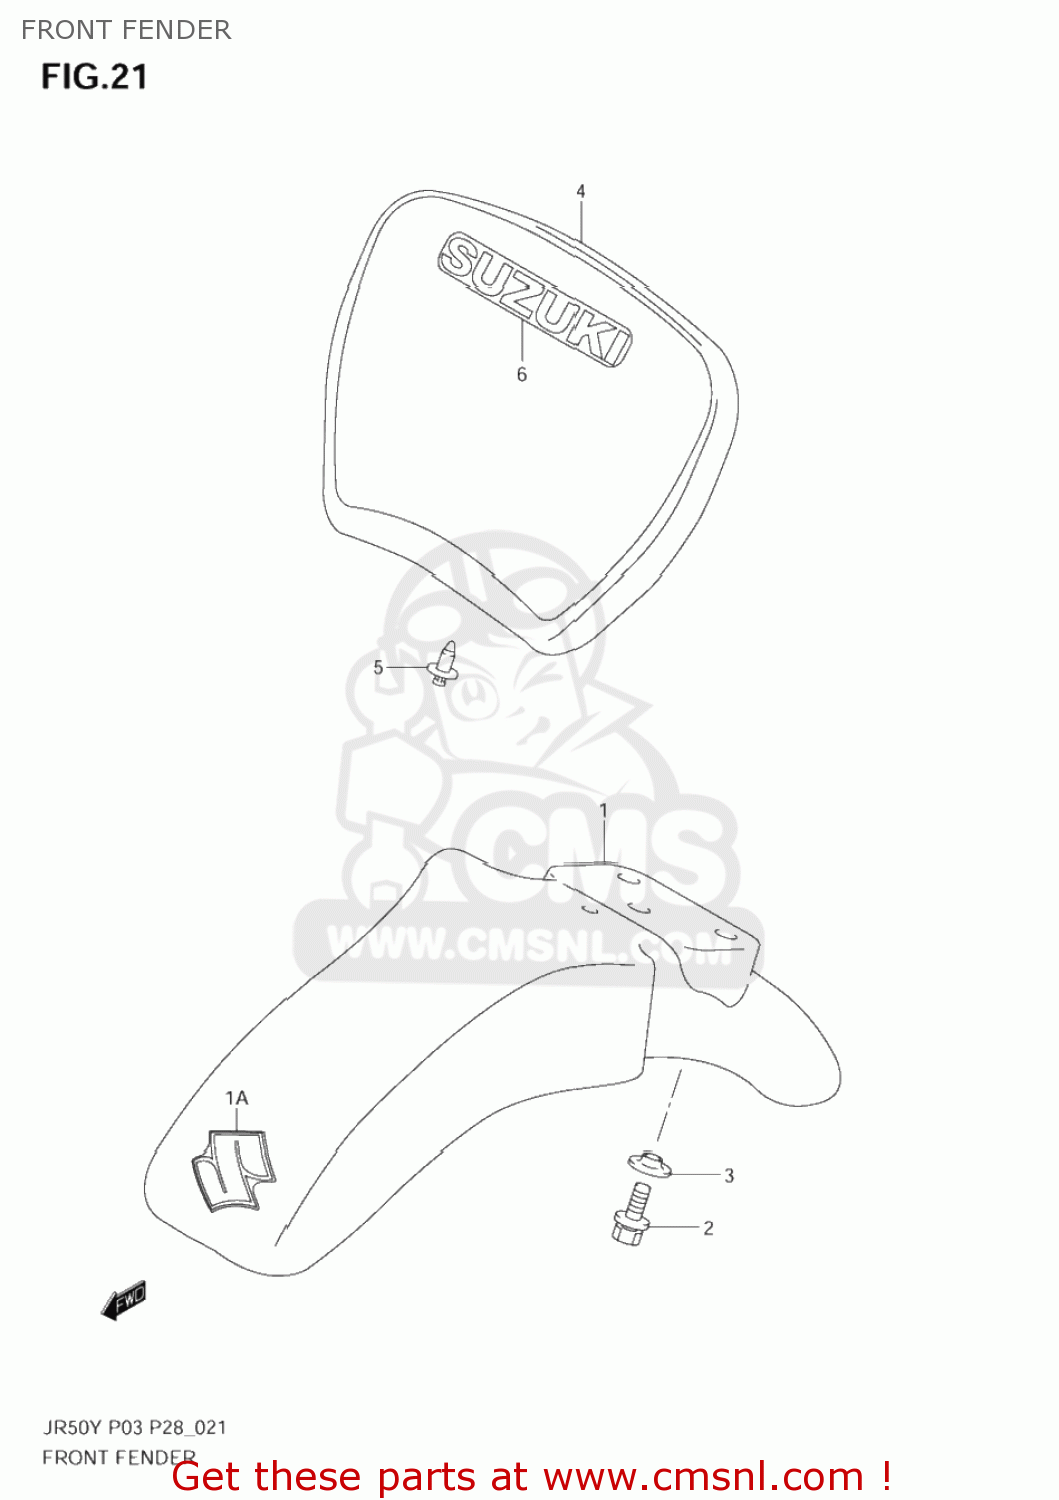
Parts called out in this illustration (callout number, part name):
1	FENDER,FR
1A	EMBLEM,S
2	BOLT(6X16)
3	WASHER
4	PLATE,NUMBER FR
5	CLIP(BLACK)
6	EMBLEM,SUZUKI
